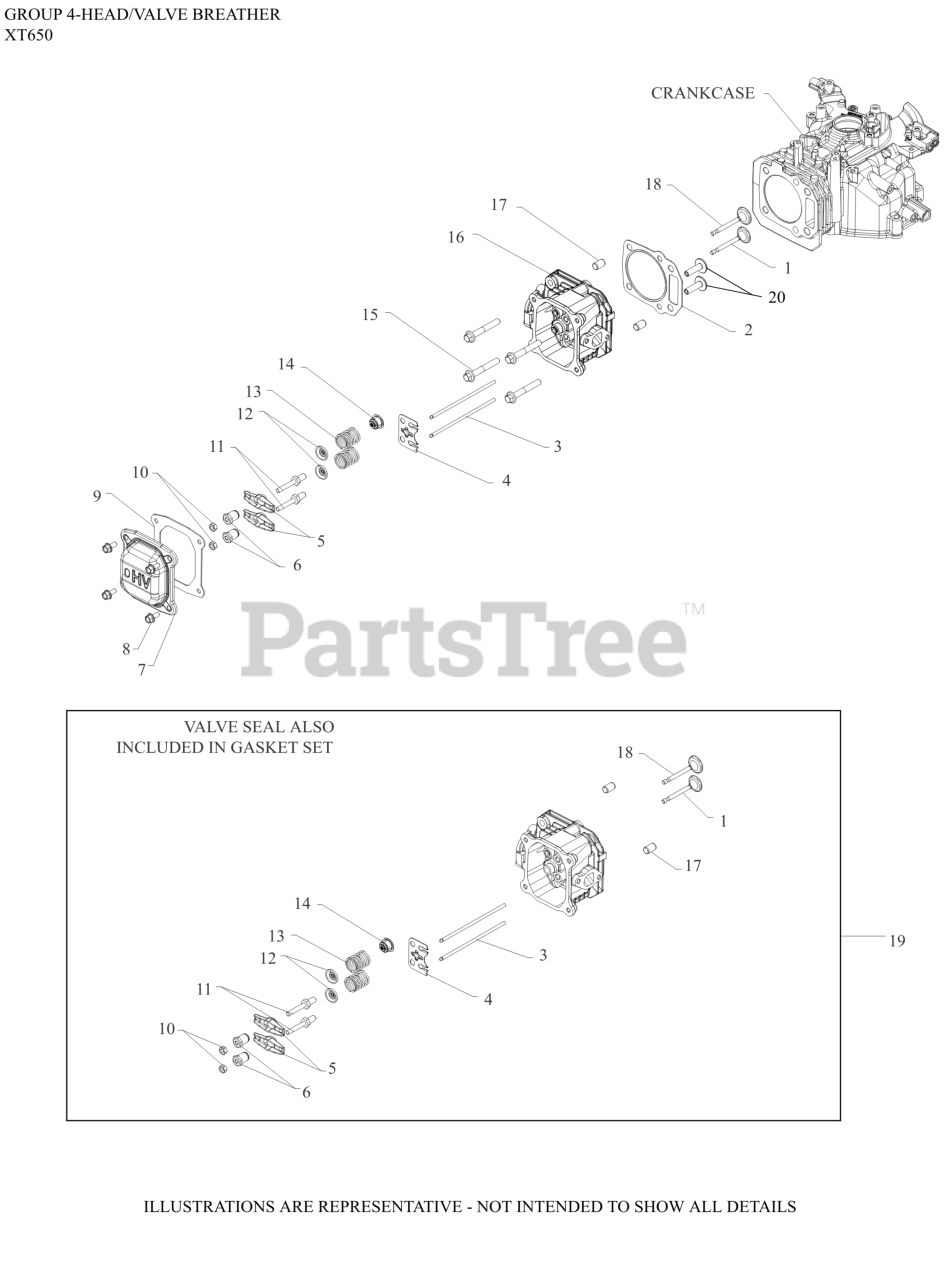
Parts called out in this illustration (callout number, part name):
1	VALVE, EXHAUST
2	KIT HEAD GASKET
3	ROD, PUSH
4	PLATE, PUSHROD GUIDE
5	ARM, ROCKER
6	PIVOT, ROCKER ARM
7	COVER, VALVE
9	GASKET, VALVE COVER
10	NUT, HEX JAM
11	STUD, ROCKER ARM-USE 14 072 22-S
12	RETAINER, VALVE SPRING
13	SPRING, VALVE
14	SEAL, VALVE STEM
15	SCREW, HEX FLANGE M8
16	KIT, CYLINDER HEAD
17	DOWEL, CYLINDER HEAD-(#1438013S)
18	VALVE INTAKE
19	KIT, VALVE TRAIN
20	LIFTER, VALVE
